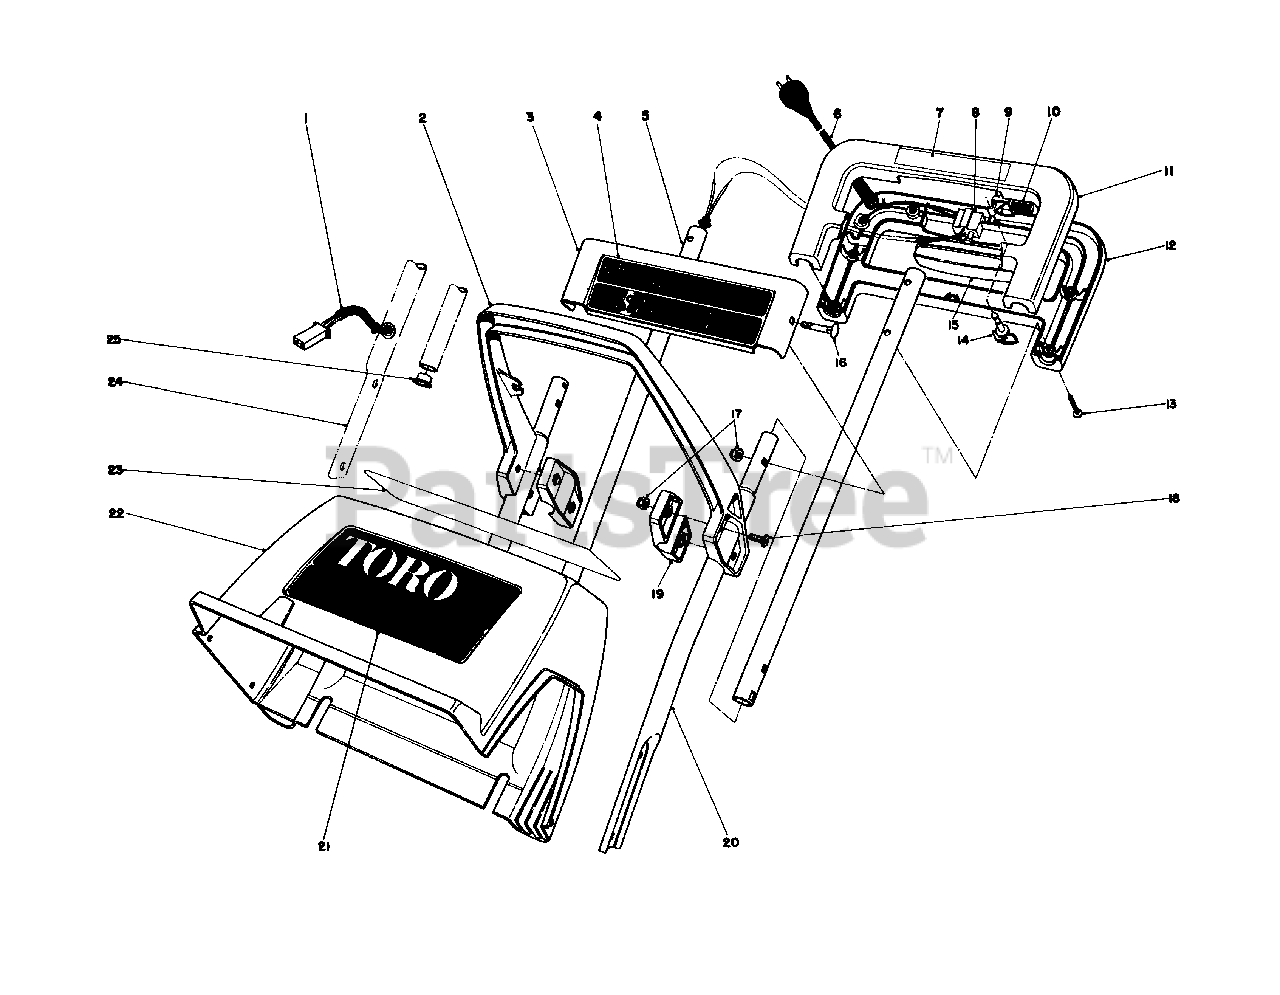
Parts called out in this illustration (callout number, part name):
1	Wire Harness
2	Middle Handle
3	Escutcheon Plate
4	Decal-Electric
5	Upper Tube
6	Cord Supply
7	Decal-Handle
9	Lockout-Switch
10	Spring Compression
11	Handle-Upper Control
12	Handle-Lower Control
13	Screw
15	Switch Bar
16	Carriage Bolt
18	Screw-Round Head
19	Clamp-Middle Handle
20	Handle-Lower LH.
21	Decal-Toro S-120
22	Shroud-S-120
23	Decal-U.L
24	Handle-Lower R.H.
25	Snap Bushing
